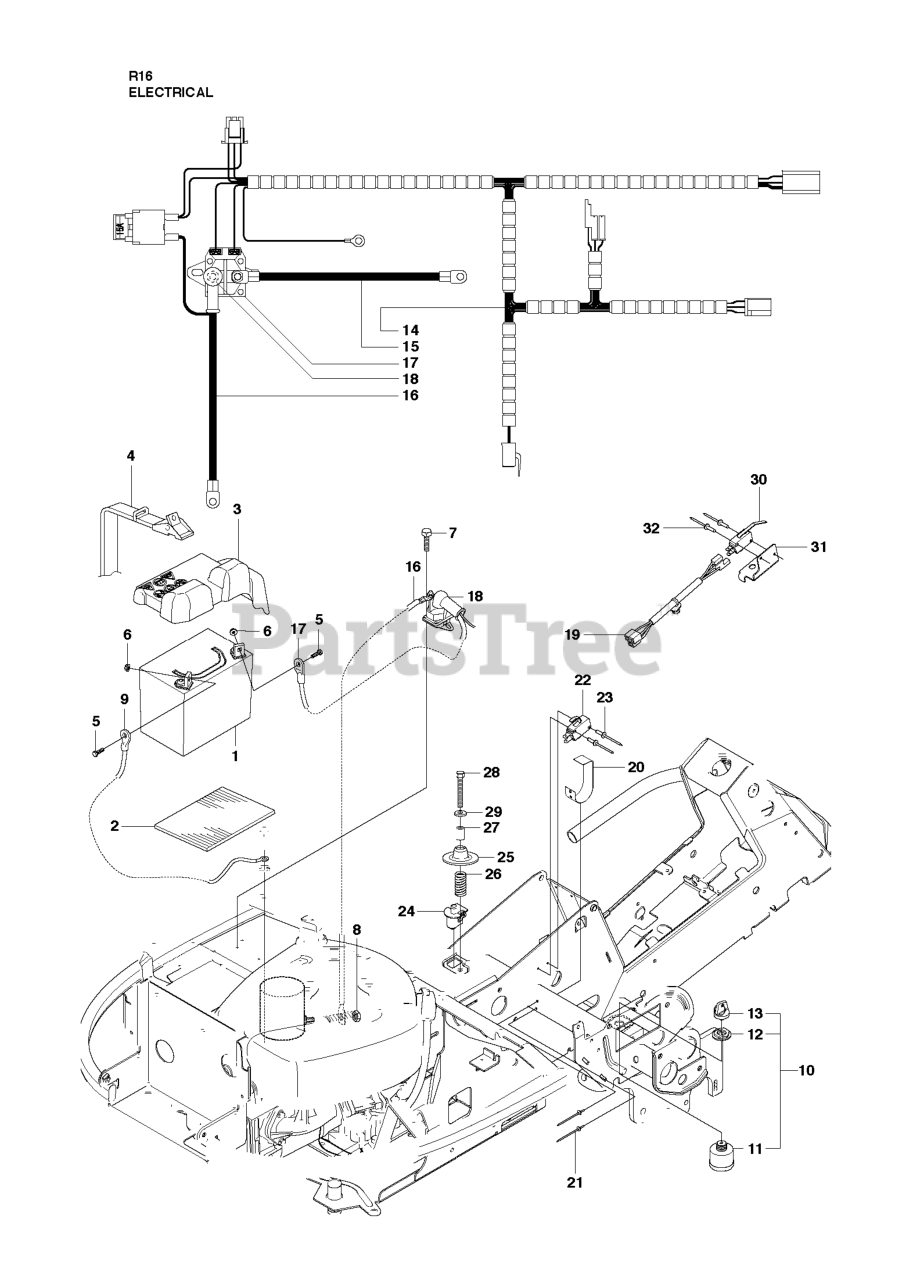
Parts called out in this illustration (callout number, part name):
5	SCREW EHHM
10	IGNITION SWITCH
11	IGNITION SWITCH
13	IGNITION KEY
19	WIRING
22	%BRAKER
27	SPACER TUBE
28	SCREW
29	WASHER BRB 8.4X17
30	RP MICRO SWITCH
